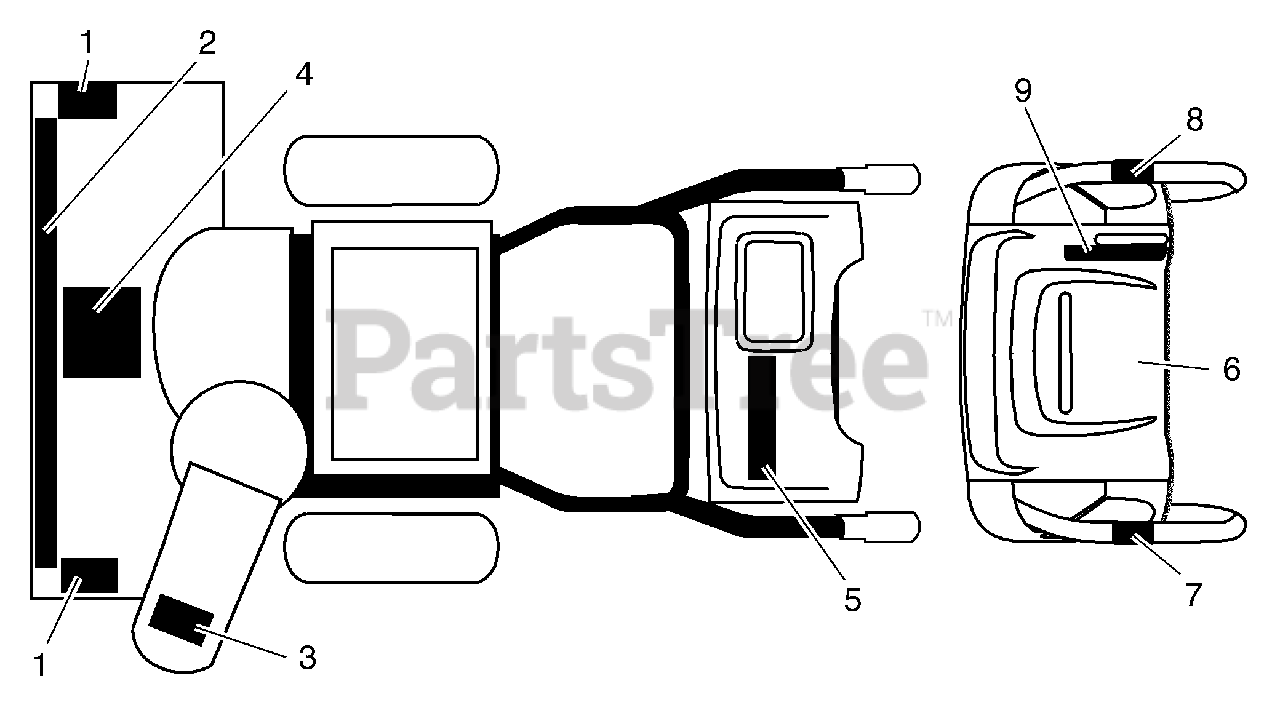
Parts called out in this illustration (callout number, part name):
1	Decal, Danger
2	Decal, Poulan Pro, 8.5HP/27" (large)
3	Decal, Danger, Deflector
4	Decal, Danger
5	Decal, Poulan Pro, 8.5HP/27" (small)
6	Decal, Instruction
7	Decal, Traction Lever
8	Decal, Auger Lever
9	Decal, Speed Control
